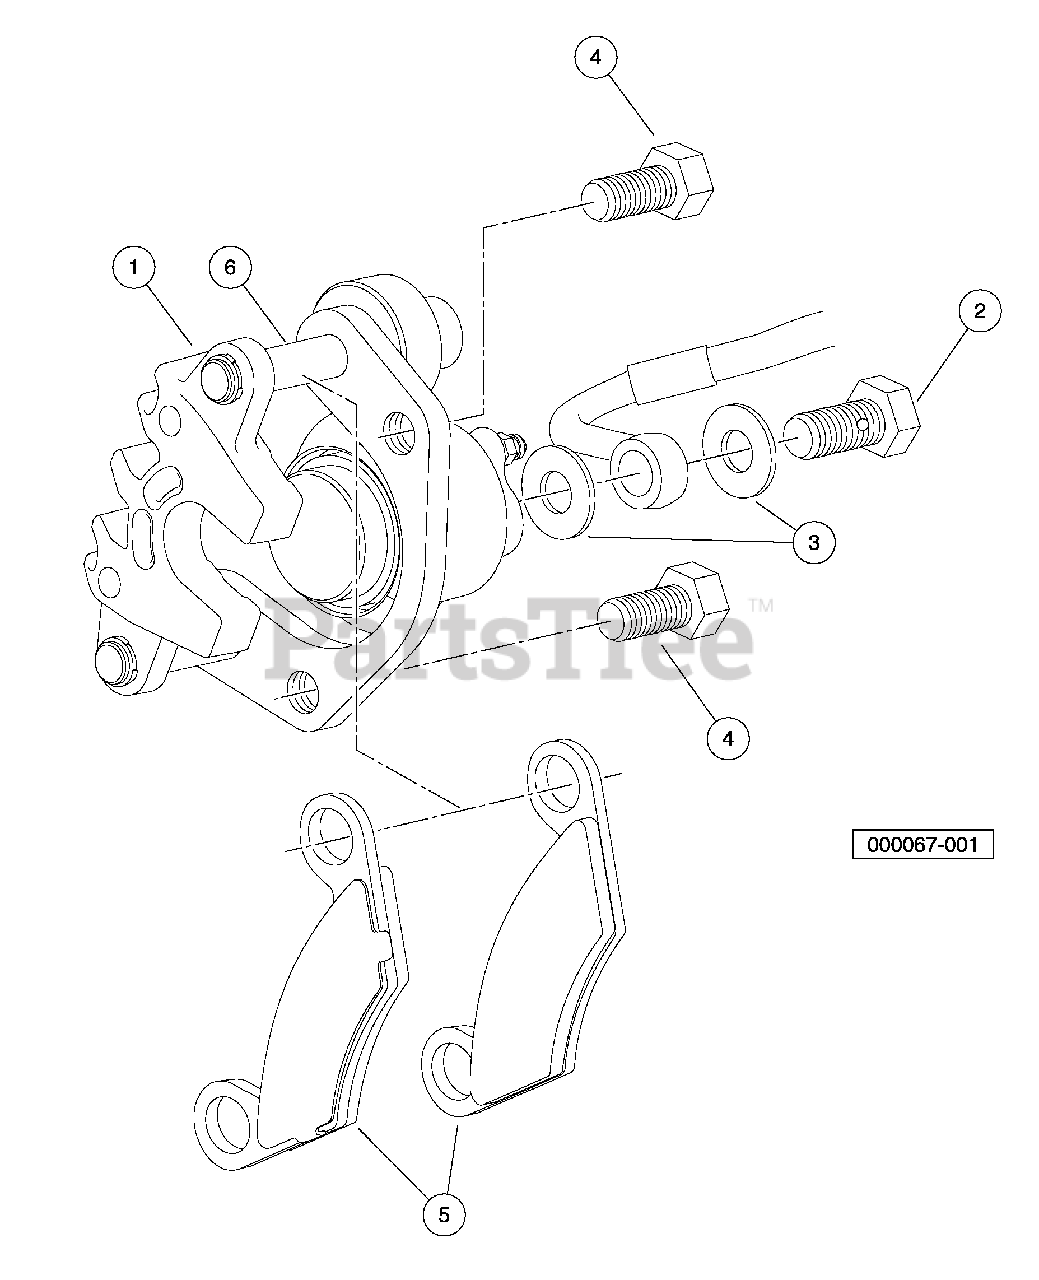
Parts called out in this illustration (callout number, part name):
1	Brake Caliper, Front, with Brake Pads
2	Bolt, Banjo, M10x1x19
3	Washer, Copper, M10 Crush
4	Bolt Flange Head, 3/8-24x.750 with Loctite
5	Service Kit, Brake Pad
6	Pin, Slide, 7/16
